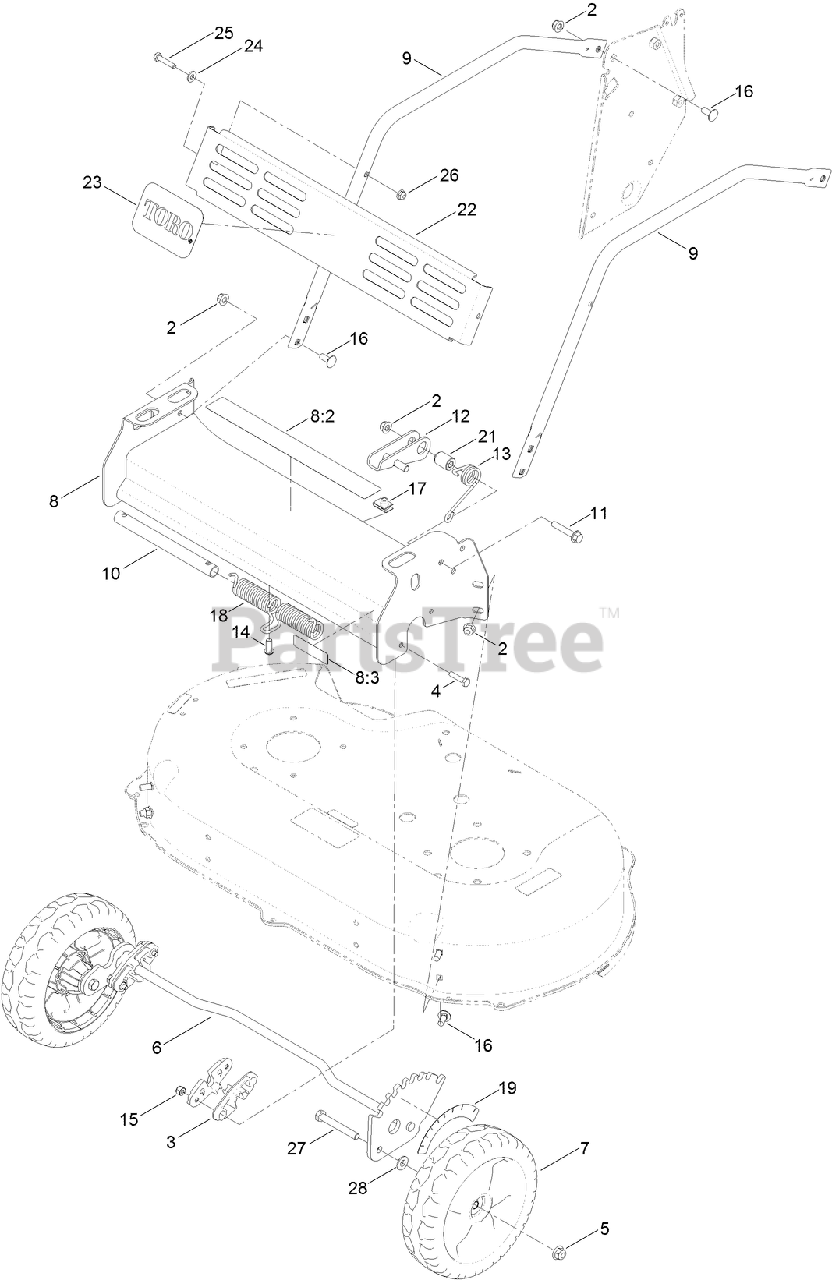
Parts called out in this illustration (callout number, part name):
2	NUT-HF, NI
3	BUSHING-FRONT
4	SCREW-HH
5	NUT-HF, NI
6	AXLE-FRONT
7	WHEEL
8	FRONT BUMPER ASM
8:3	DECAL-WARNING
10	MANDRELL-SPRING
11	SCREW-HWH
12	LOCK-HEIGHT, ADJUSTMENT
13	SPRING-TORSION
14	SCREW-HSBH
15	NUT-LOCK, NI
16	SCREW-CARR
17	NUT-U
18	SPRING-TORSION
19	DECAL-HOC, FRONT
21	SPACER
24	WASHER-FLAT
25	SCREW-HH
26	NUT-HF
27	SCREW-HH
28	SPACER-COVER, WHEEL
